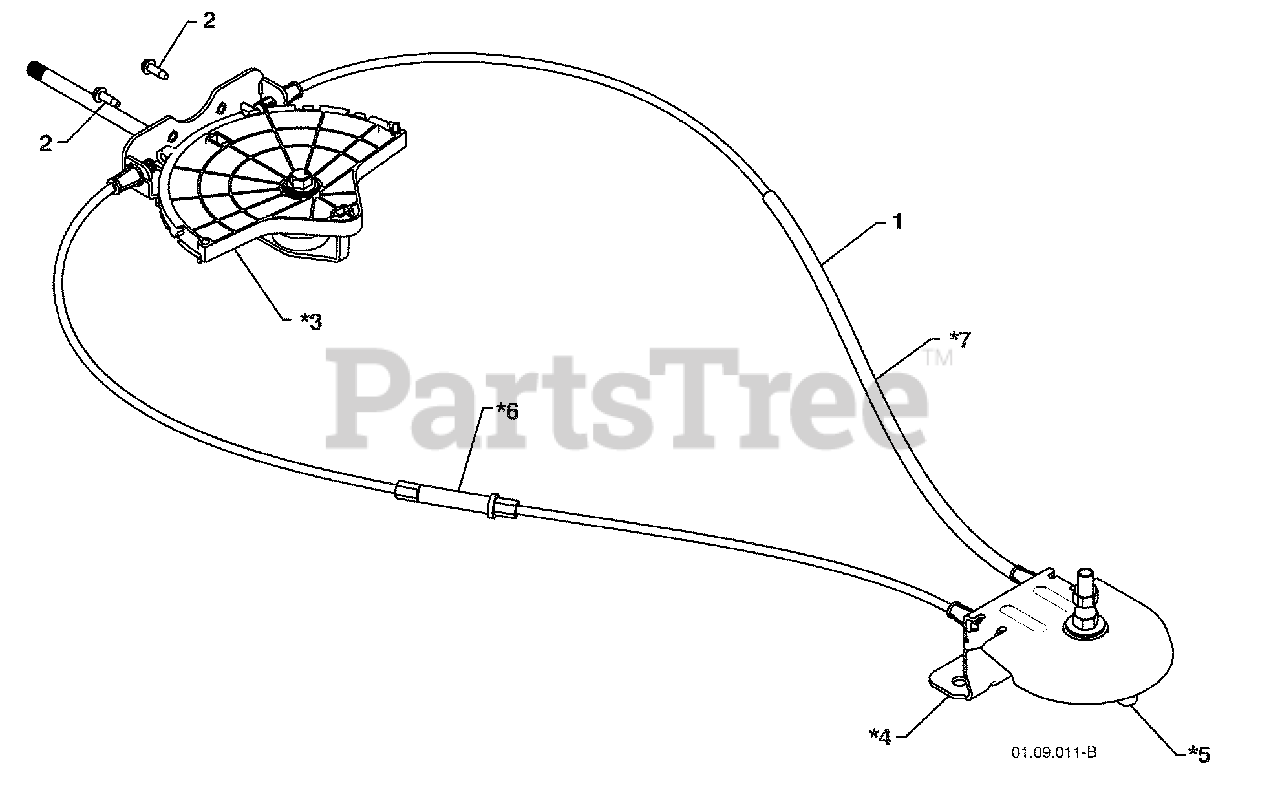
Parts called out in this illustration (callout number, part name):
1	LEVER/CABLE ROTATOR ASSEMBLY
2	SCREW 10-24 X .625
3	ROTATOR HEAD
4	ROTATOR PIVOT BRACKET
5	PULLEY PIVOT
6	CABLE ASSEMBLY ADJUSTABLE GRAY
7	CABLE ASSEMBLY HEAT SHIELD GRAY
